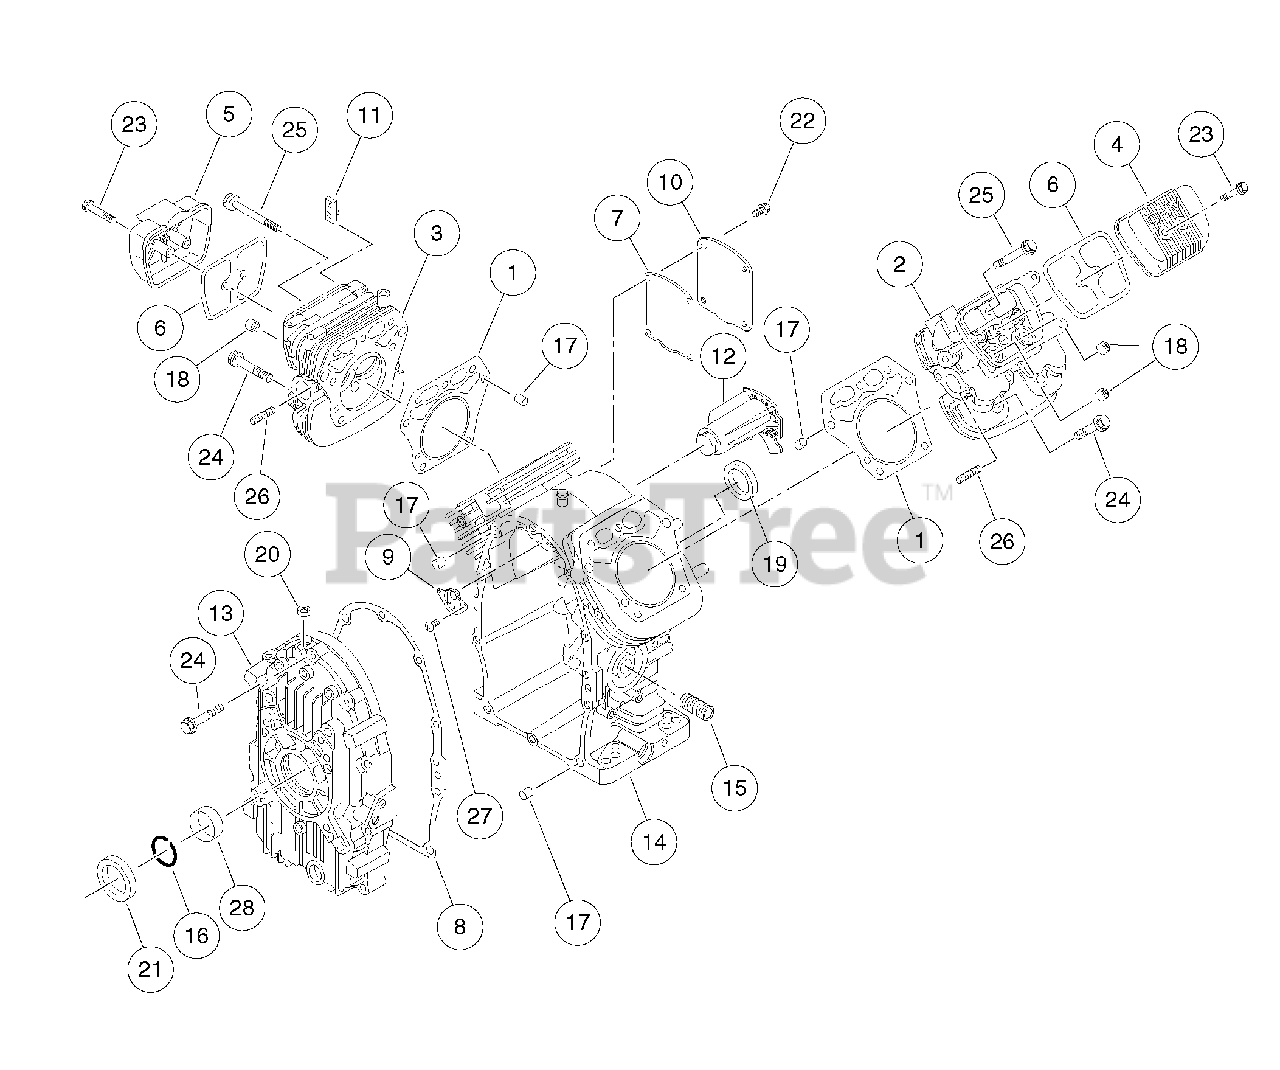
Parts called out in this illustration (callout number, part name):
1	Gasket, Head, Cyl, Fh
2	Head, Cyld 1, Fh
3	Head, Cyld 2, Fh
4	Cover, Rocker, Cyld 1, Fh
5	Cover, Rocker, Cyld 2, Fh
6	Gasket, Rocker, Cover, FH
7	Gasket, Breather, Fh
8	Gasket, Cover, Crank, Fh
9	Valve, Assy, Reed, Fh
10	Cover, Crkcase, Comp, Fh
11	Pipe, Head, Comp, Clyd, Fh
12	Pipe, Crkcase, Comp, Fh
13	Cover, Crankcase, Fh
14	Crankcase, Comp, Fh
15	Nipple, Oil Filter, Fh
16	Ring, Snap, Fh
17	Pin, Head, Fh
18	Seal, Oil, Valve, Fh
19	Seal, Oil, Crank, Rear, Fh
20	Seal, Oil, Governor, Fh
21	Seal, Oil, Crank, Front, Fh
22	Bolt, Flg, M6 X 1.0 X 12
23	Bolt, Flg, M6 X 1.0 X 40
24	Bolt, Flg, M8 X 1.25 X 50
25	Bolt, Flg, M8 X 1.25 X 75
26	Stud, M8 X 1.25, Exhaust, Fh
27	Screw, Pan, Governor, Fh
28	Bushing, Main, Fh
